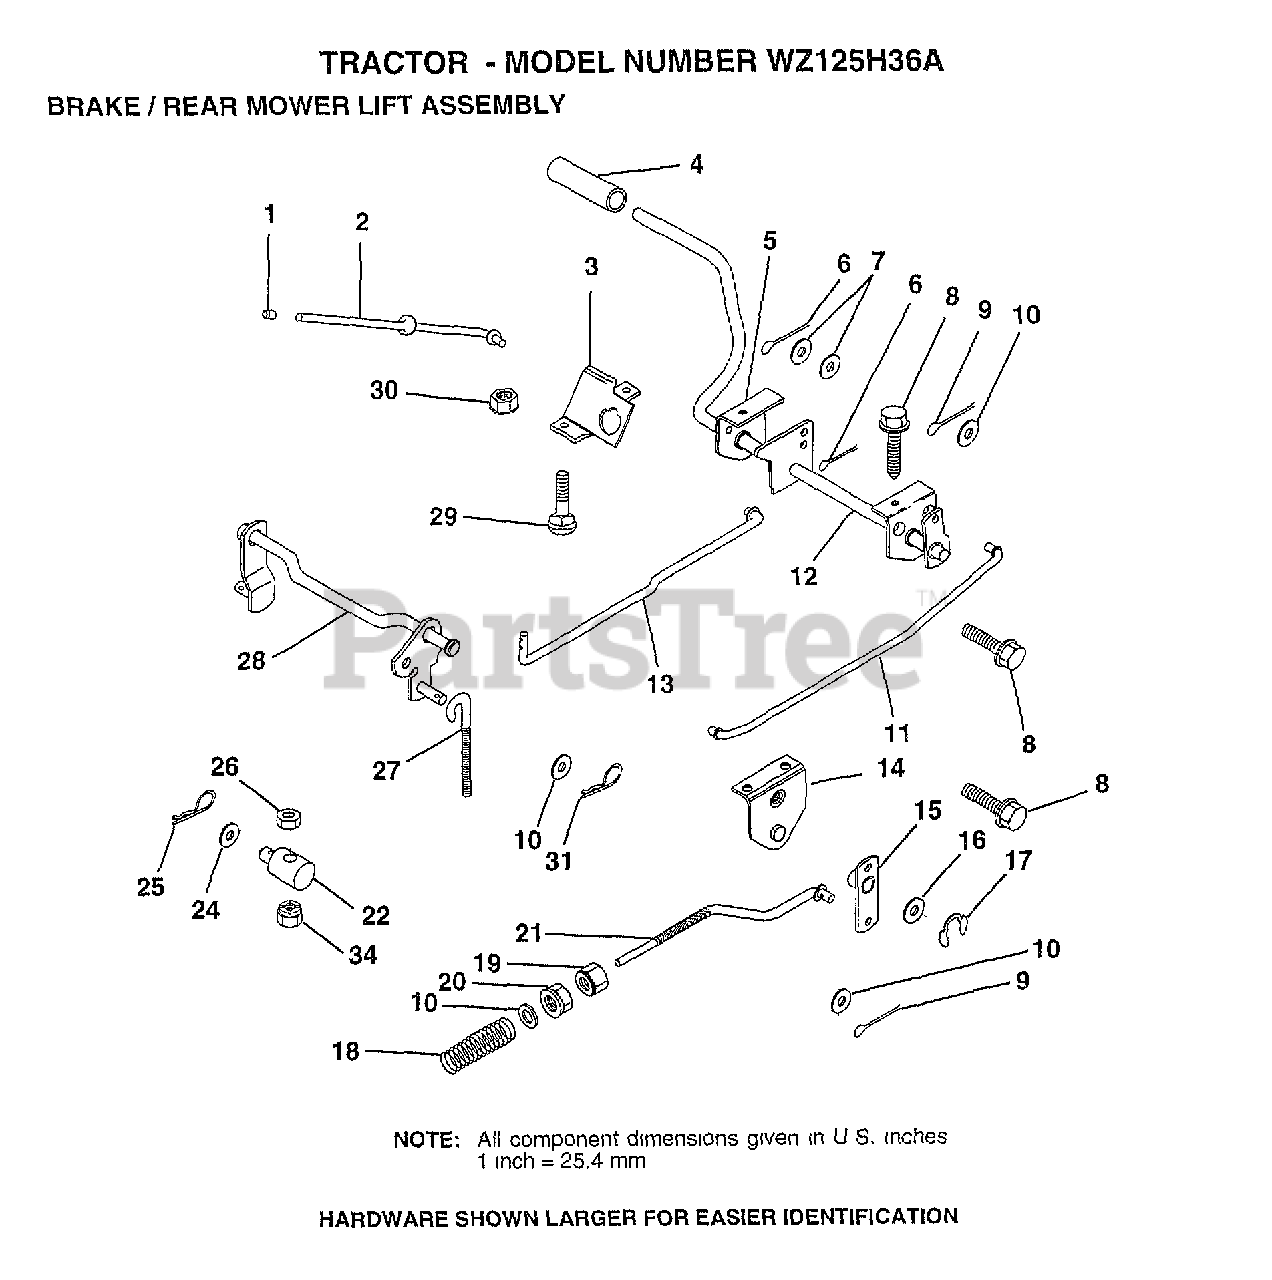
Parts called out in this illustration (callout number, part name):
1	PLUNGER CAP T
2	"ROD,PARK BRAKE"
3	"BRKT,PARK BRAKE"
4	FOOT PEDAL COVER
5	"BRKT,CLU PEDAL LH"
7	WASHER
8	SCREW LT
9	COTTER PIN
10	WASHER
11	"ROD,FRT BRAKE"
12	PEDAL ASM CL/BK36
13	"ROD,CLUTCH"
14	"BRKT,LIFT SHAFT"
15	PVT BRAKE ARM ASM
16	WASHER T
17	KLIP RING
18	SPRING ROD BRAKE
19	NUT
20	NUT
21	ROD.BRAKE.HYDRO
22	TRUNNION.LIFT.
24	WASHER
26	LOCKNUT
27	"LINK, MOWER REAR"
28	LIFT ASM MOW REAR
31	RETAINER.SPRING
